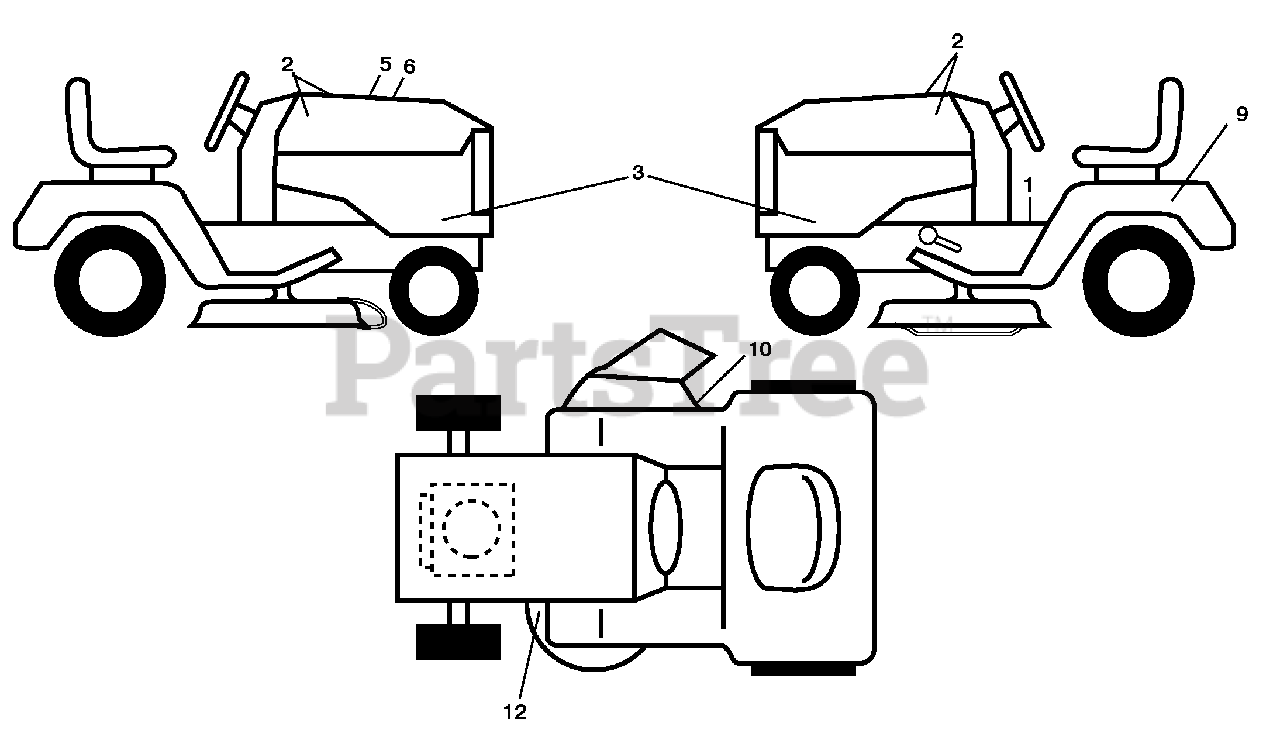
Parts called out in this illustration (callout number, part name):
1	Decal, Operators
2	Decal, Badge
3	Decal, Hood Panel SD
5	Decal, Customer Respons.
6	Decal, Replacement
9	Decal, Battery Dnge/Poi
10	Decal, Warning
12	Decal, Mower V-Belt Schematic
